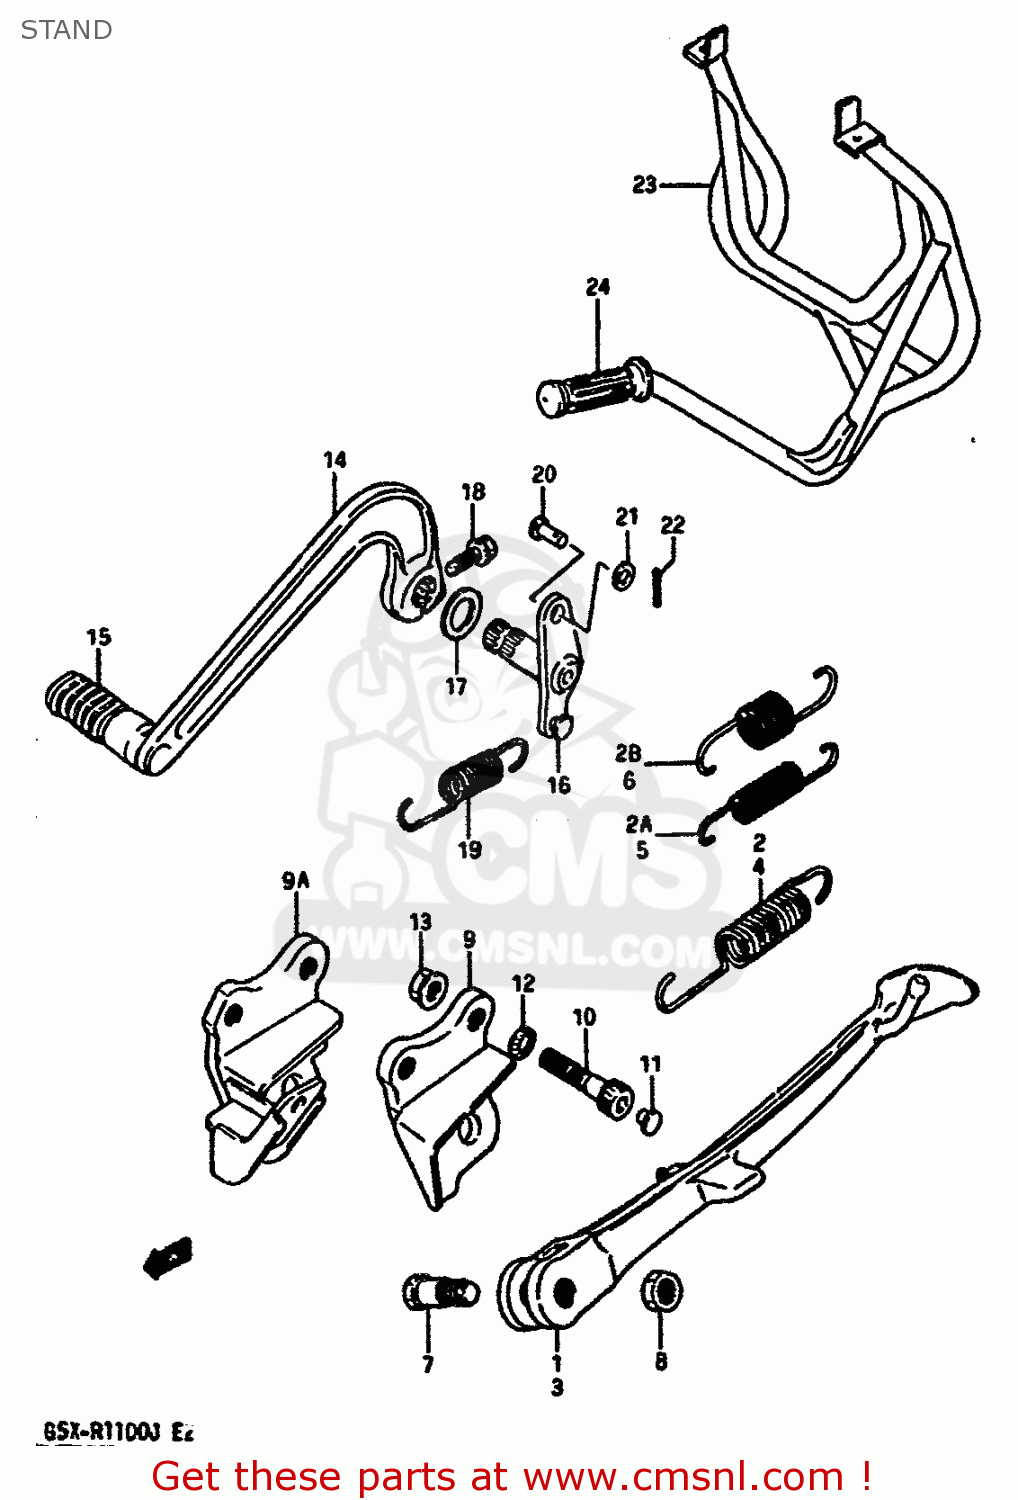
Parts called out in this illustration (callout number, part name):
1	STAND,PROP
2	SPRING
2A	SPRING
2B	SPRING
3	STAND,PROP (SILVER)
4	SPRING
5	SPRING
6	SPRING
7	BOLT(10X38)
8	NUT
9	BRACKET,PROP STAND
9A	BRACKET,PROP STAND
10	BOLT, FRONT RH
11	CAP,ENGINE MOUNTING
12	WASHER
13	NUT
14	PEDAL,BRAKE
15	RUBBER,BRAKE PEDAL
16	ARM COMP,BRAKE ROD
17	WASHER,BRAKE PEDAL
18	BOLT
19	SPRING
20	PIN
21	WASHER
22	PIN
23	STAND,CENTER
24	GRIP,L
